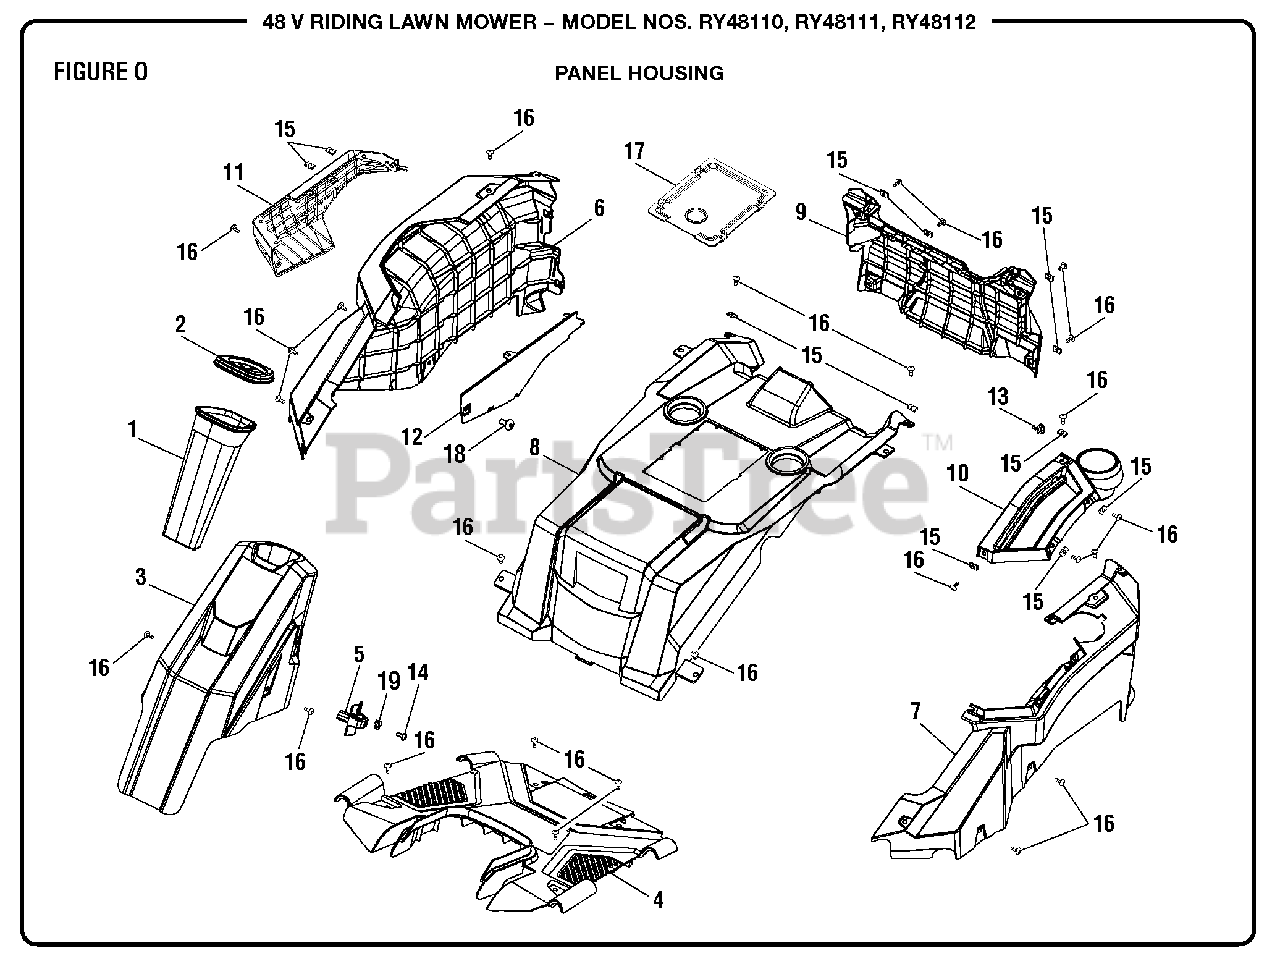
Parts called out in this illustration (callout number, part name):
1	Upper Steering Column
2	Steering Column Cover
3	Lower Steering Column
4	Floor Pan
5	Parking Brake Lever
6	Right Fender Housing
7	Left Fender Housing
9	Rear Mover Cover
10	Deck Lift Console
12	Rear Console Cover
13	Indicator Flag
14	Screw (M4 x 10 mm, Pan Hd.)
15	Clip-On Nut (M6)
16	Screw (M6 x 16 mm, Torx Soc. Hd.)
17	Battery Access Cap
18	Screw (ST4.2 x 13 mm)
19	Adjusting Washer
